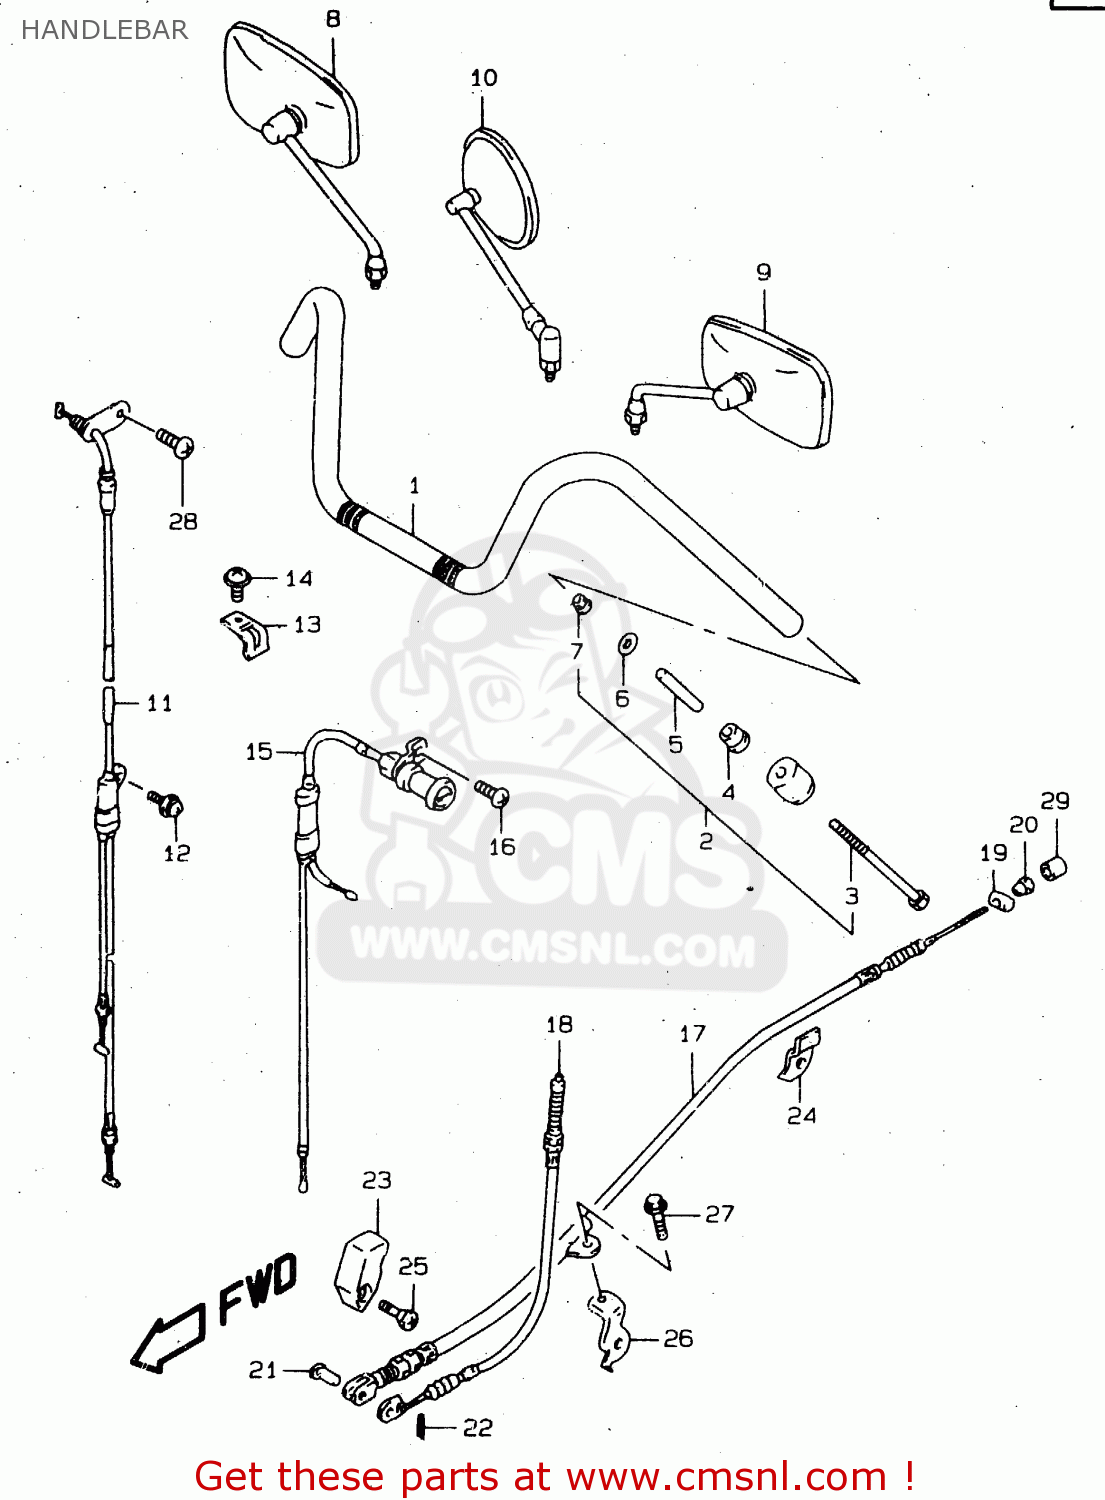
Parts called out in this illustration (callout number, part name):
1	HANDLEBAR
2	BALANCER SET,HANDLEBAR
3	SCREW(6X110)
4	EXPANDER,HANDLE BALANCER NO.2
5	SPACER,EXPANDER
6	WASHER (6.5X18X2)
7	NUT
8	MIRROR ASSY,RR VIEW,R
9	MIRROR ASSY,RR VIEW,L
10	MIRROR ASSY,RH
11	CABLE ASSY,THROTTLE
12	SCREW
13	CLAMP,THROTTLE CABLE
14	SCREW
15	CABLE ASSY,STARTER
16	SCREW 6X10
17	CABLE,RR BRAKE
18	CABLE,STOP LAMP SWITCH
19	PIN(13X18)
20	NUT
21	PIN(L:17.5)
22	PIN
23	GUIDE,RR BRAKE CABLE
24	CLAMP,RR BRAKE CABLE
25	SCREW
26	BRACKET,RR BRAKE CABLE
27	BOLT
28	SCREW
29	CAP,GREASE NIPPLE
